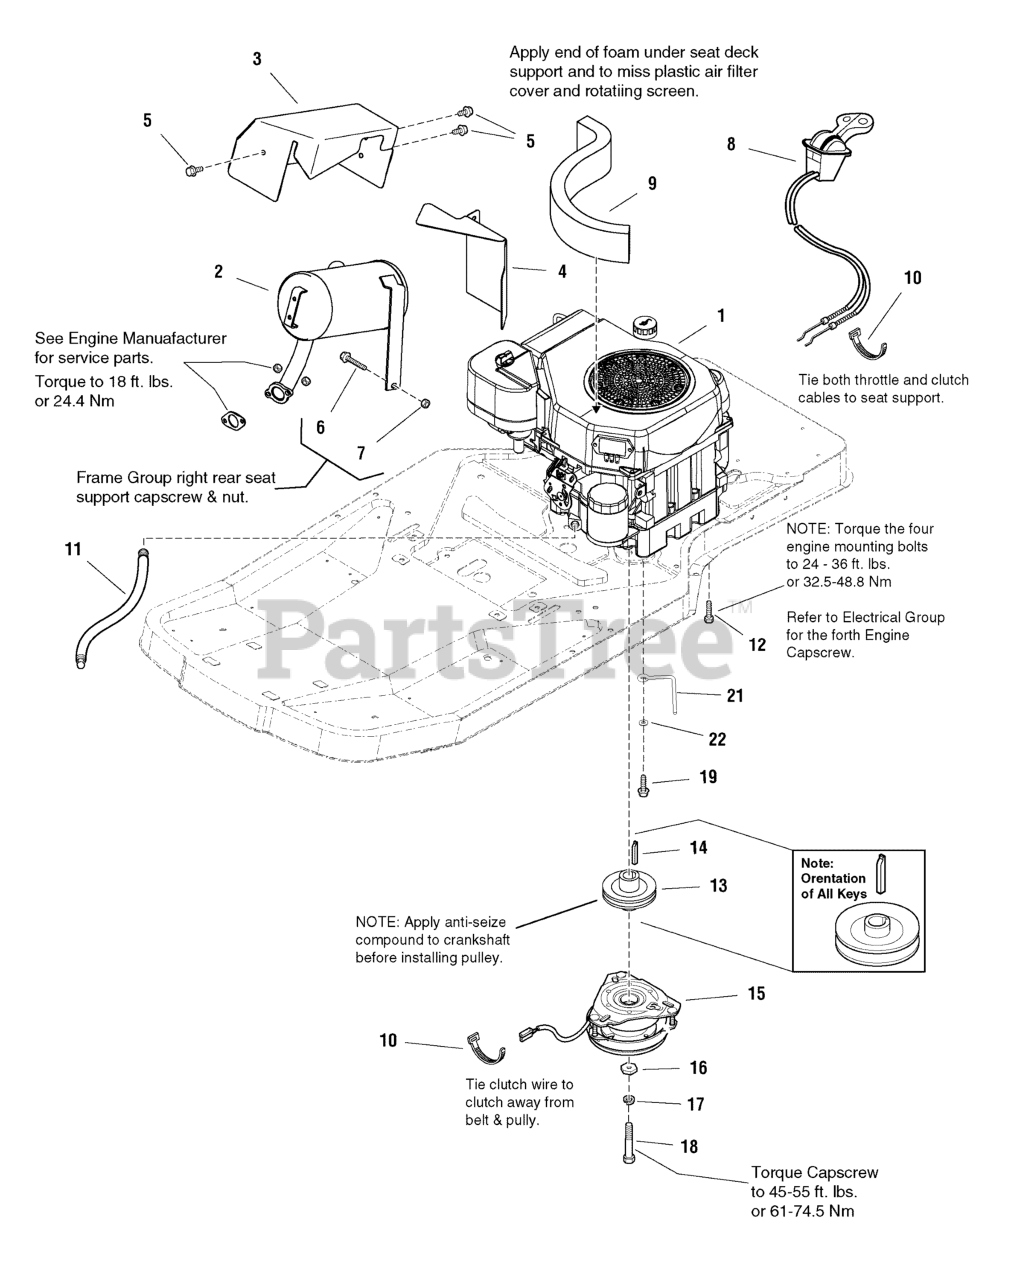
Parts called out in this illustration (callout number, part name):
1	ENGINE, 20HP, KOHLER Courage
2	MUFFLER, Kohler 20HP Courage ZT 7000
3	SHIELD & INSULATION ASSEMBLY, Muffler, Heat Top
4	SHIELD, Muffler, Heat Side
5	SCREW, Hex Washer Head, Taptite, 5/16-18 x 1/2
6	CAPSCREW, Hex Head Flange Lock, 5/16-18 x 1-1/4
7	NUT, Hex Flange Whiz Lock Small, 5/16-18
8	CONTROL, Throttle Double 42" Long
9	SEAL, Foam, 1 x 2-1/2, 12" LG Curved
10	TIE, Self Locking, 3-5/8 LG
11	HOSE, Oil Drain
12	SCREW, Hex Washer Head, Taptite 3/8-16 x 2
13	PULLEY, 3.74 OD x 1.003 ID x 1.88 LG
14	KEY, Hi-Pro, 1/4 x 2-1/2
15	CLUTCH, Electric Ogura
16	WASHER, Hex
17	LOCKWASHER, Spring, 7/16
18	CAPSCREW, Hex Head Cap, 7/16-20 x 2-3/4, GR5, Black
19	CAPSCREW, Hex Washer Head, Taptite, 3/8-16 x 3/4
21	RETAINER, Clutch
22	WASHER, 3/8, .41 ID x .87 OD x .08 THK
